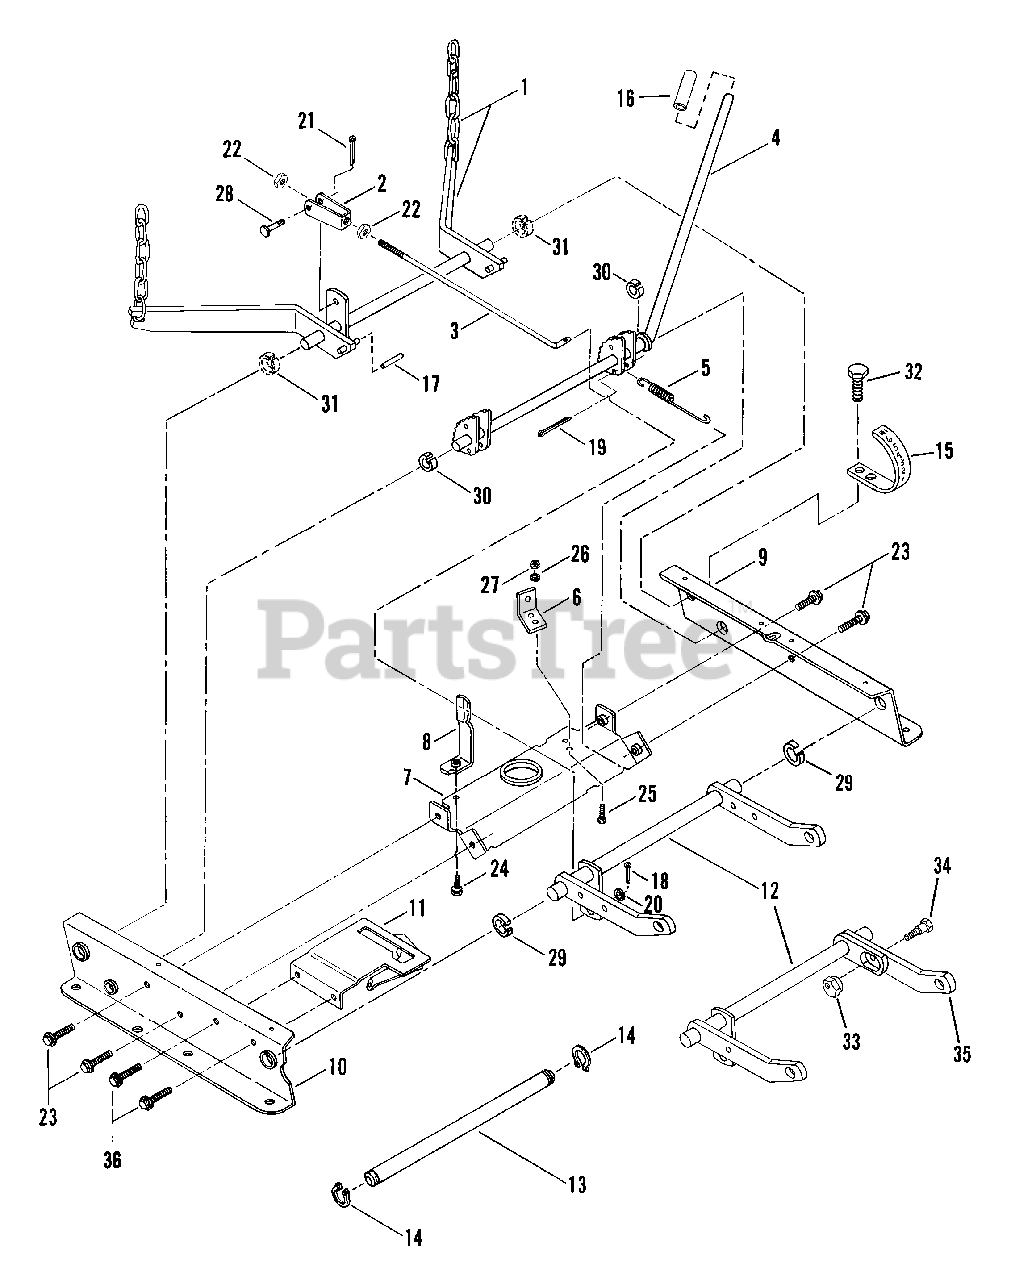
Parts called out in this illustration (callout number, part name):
1	ASSEMBLY, REAR LIFT ARM (28,30" MODELS)
2	CLEVIS, Timing Rod
3	TIMING ROD (5/8" x 12.38")
4	CAM LIFT LEVER
5	SPRING, Cam Lift
6	ANCHOR (Auto. Blade Control Models)
7	BRACE, Top
8	GUIDE, Belt
9	RAIL, Left Hand
10	RAIL, Right Hand
11	ASSEMBLY, Clutch-Plate
12	FRONT LIFT ARM (Non-Adjustable 28" & 30" Models)
12	FRONT LIFT ARM (Adjustable-All 33" Models)
13	SUPPORT ROD (Front Lift Arm to Front End)
14	RING, 5/8" External Retaining
15	PLATE, Indicator
16	GRIP, Height Adjustment Lever
17	PIN, Roll (Part of item 1)
18	PIN, 1/8x3/4" Cotter
19	PIN, 5/32x1" Cotter
20	WASHER, 3/8" Flat
21	PIN, 3/32x3/4" Cotter
22	NUT, 3/8-24 Hex
23	SCREW, 3/8-16x1" Hex Self-Tapping
24	SCREW, 5/16-18x5/8" Hex Self-Tapping
25	SCREW, 5/16-24x3/4" Hex Head Cap
26	LOCKWASHER, 5/16 Internal Tooth Lock
27	NUT, 5/16-24 Hex
28	PIN, 3/8 x 1 1/16" Clevis
29	RING, Red
30	RING, White
31	RING, Blue
32	SCREW, 3/8-24x3/4" Hex Head Cap
33	ECCENTRIC, Leveling
34	BOLT, Shoulder
35	ARM, Front Lift-Left
36	SCREW, 5/16-18x1/2" Self-Tapping
